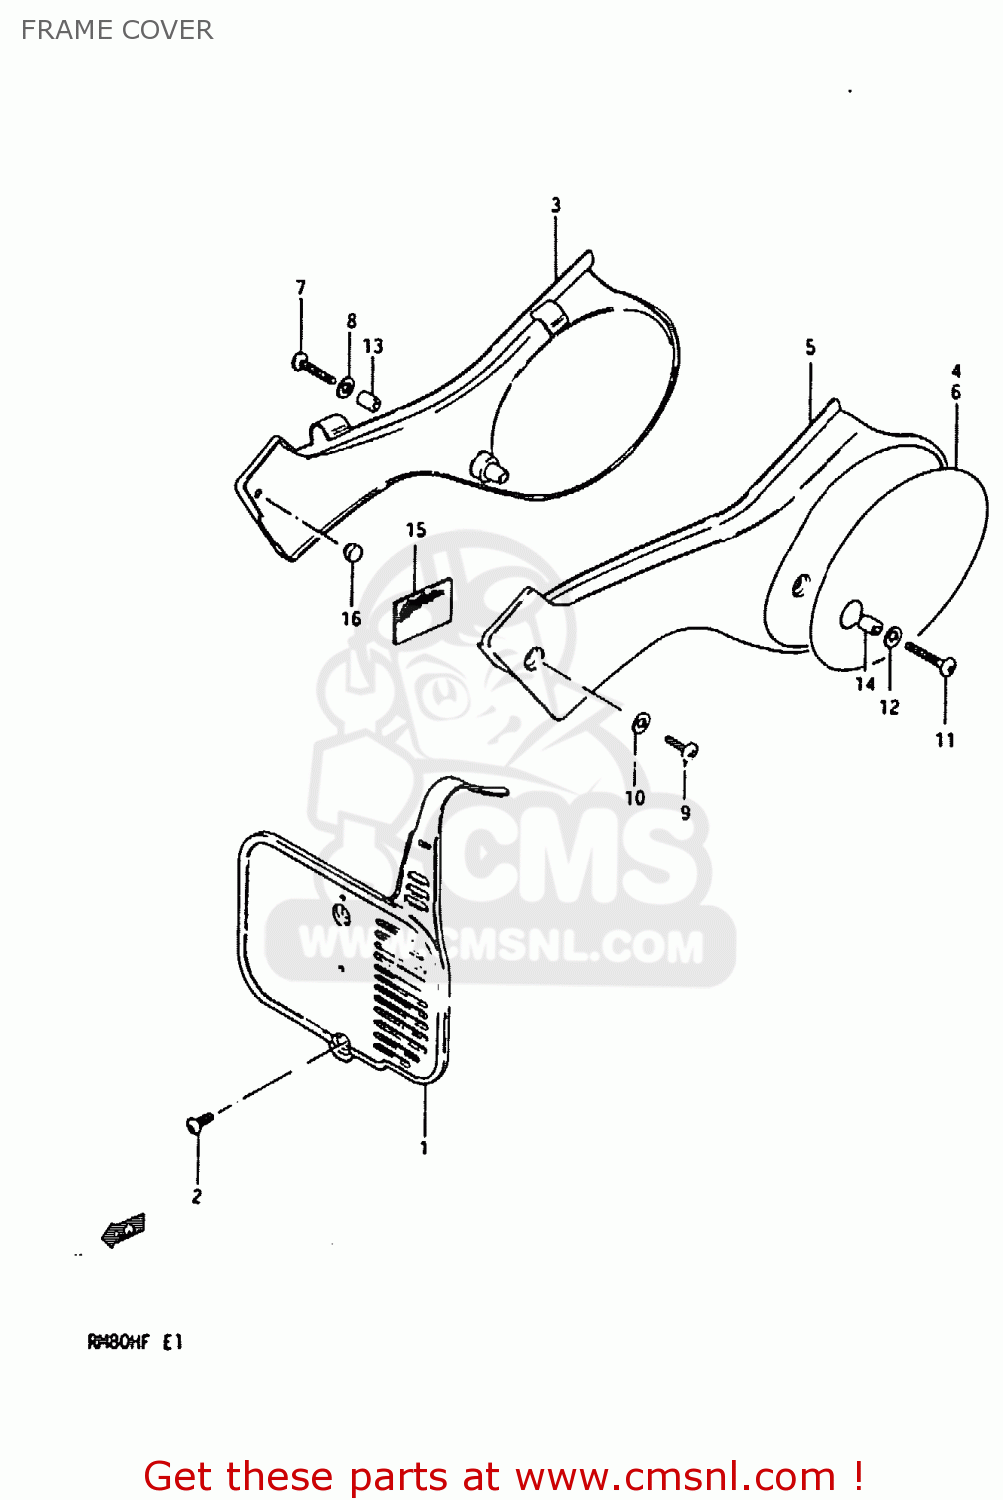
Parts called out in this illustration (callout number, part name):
1	PLATE, FRONT UMBER
2	SCREW
3	COVER, FRAME RH (YELLOW)
4	EMBLEM, RH
5	COVER, FRAME LH (YELLOW)
6	EMBLEM, LH
7	SCREW
8	WASHER (6.5X18X1.6)
9	SCREW
10	WASHER
11	SCREW
12	WASHER (6.5X18X1.6)
13	SPACER (6.4X9X20)
14	SPACER (6.5X10.5X25)
15	HEAT SHIELD,FRAME COVER
16	CUSHION
